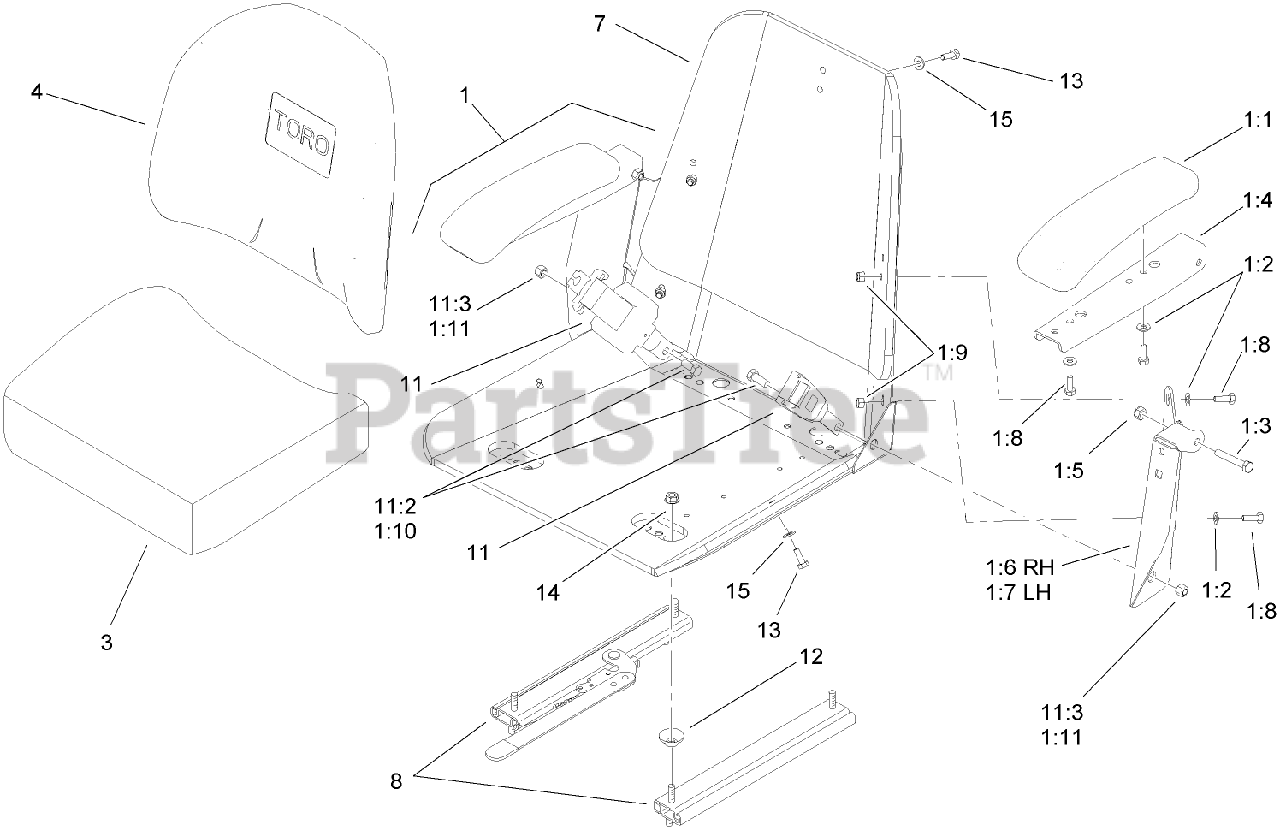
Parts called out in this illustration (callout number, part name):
1	ARMREST KIT
1:1	CUSHION-REST, ARM
1:2	WASHER-FLAT
1:3	SCREW-HH
1:4	CHANNEL-ARMREST
1:5	NUT-HEX, SIDE DEFORM
1:6	Bracket-Armrest, RH
1:7	Bracket-Armrest, LH
1:8	SCREW-HH
1:9	NUT-LOCK, NI
1:10	SCREW-HH
1:11	NUT-LOCK, NI
3	CUSHION-SEAT, BOTTOM
4	CUSION-SEAT, BACK
7	FRAME-SEAT
8	TRACK-SEAT
11	RETRACTABLE SEATBELT KIT
11:2	SCREW-HH
11:3	NUT-LOCK
12	SPACER-TRACK
13	SCREW-HH
14	NUT-HF
15	WASHER-FLAT
